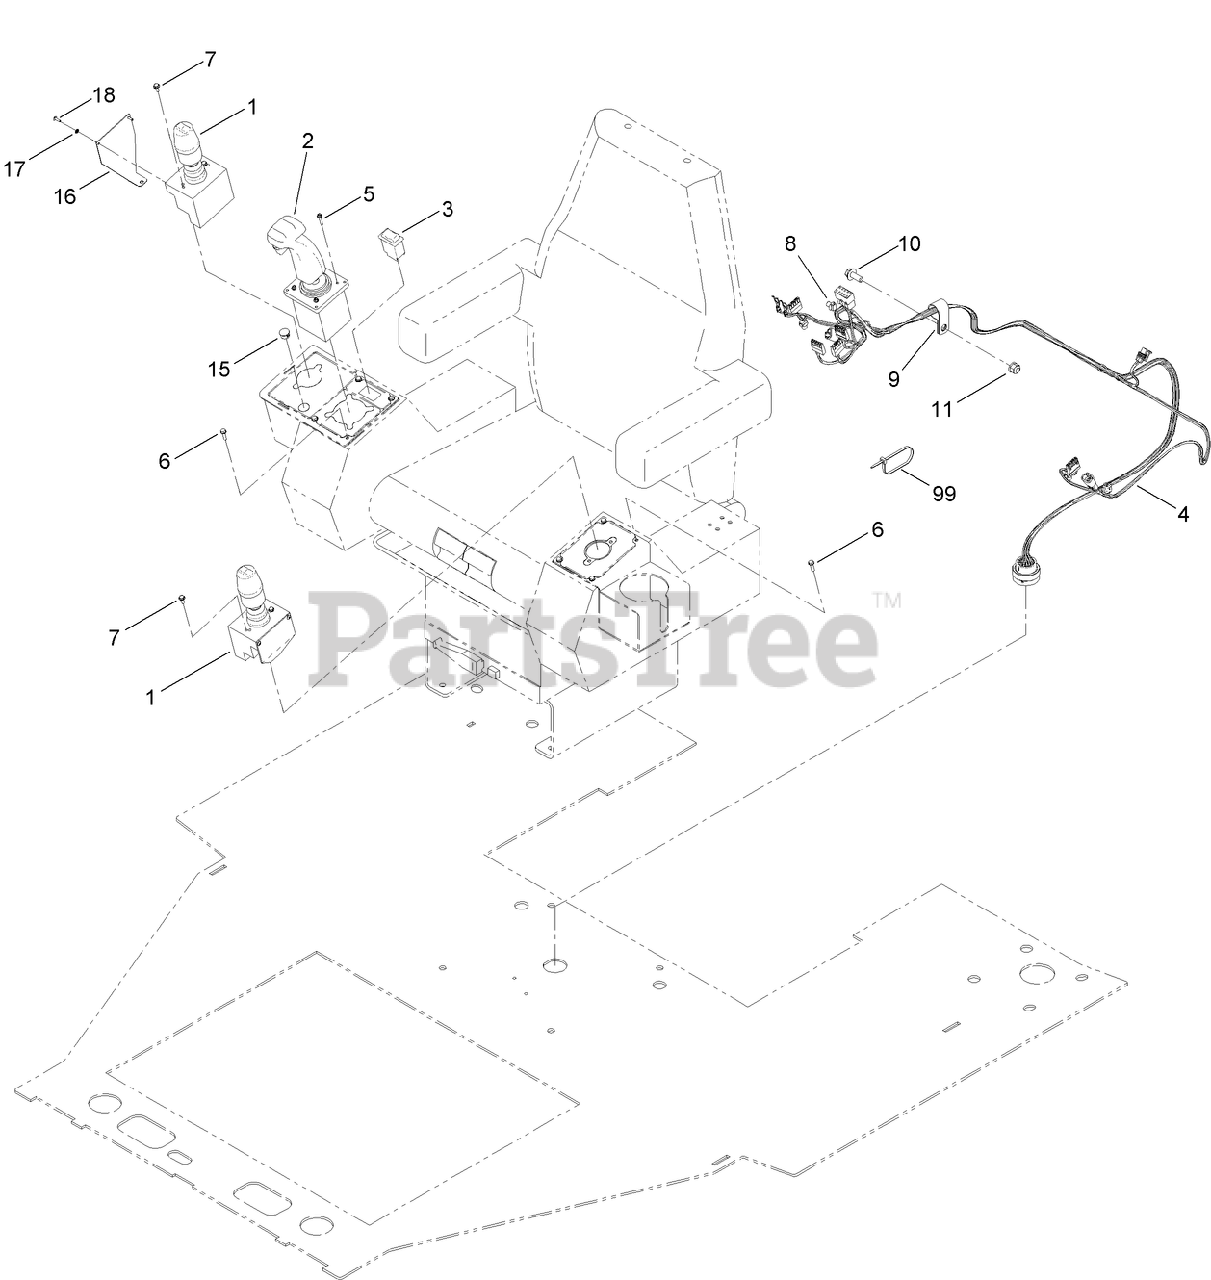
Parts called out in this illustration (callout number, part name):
1	SINGLE AXIS JOYSTICK ASM
2	JOYSTICK-CONTROL (W/ HANDLE)
3	SWITCH-ROCKER, 2 POLE
4	HARNESS-WIRE, SEAT
5	SCREW-SHWH
6	SCREW-HWH
7	SCREW-HWH
8	CLIP-TIE
9	CLAMP-R
10	SCREW-HHF
11	NUT-LOCK, NI
15	PLUG-DOME
16	PLATE-SENSOR, PEDAL
17	WASHER-LOCK / EXT
18	SCREW-PRH
99	TIE-CABLE
